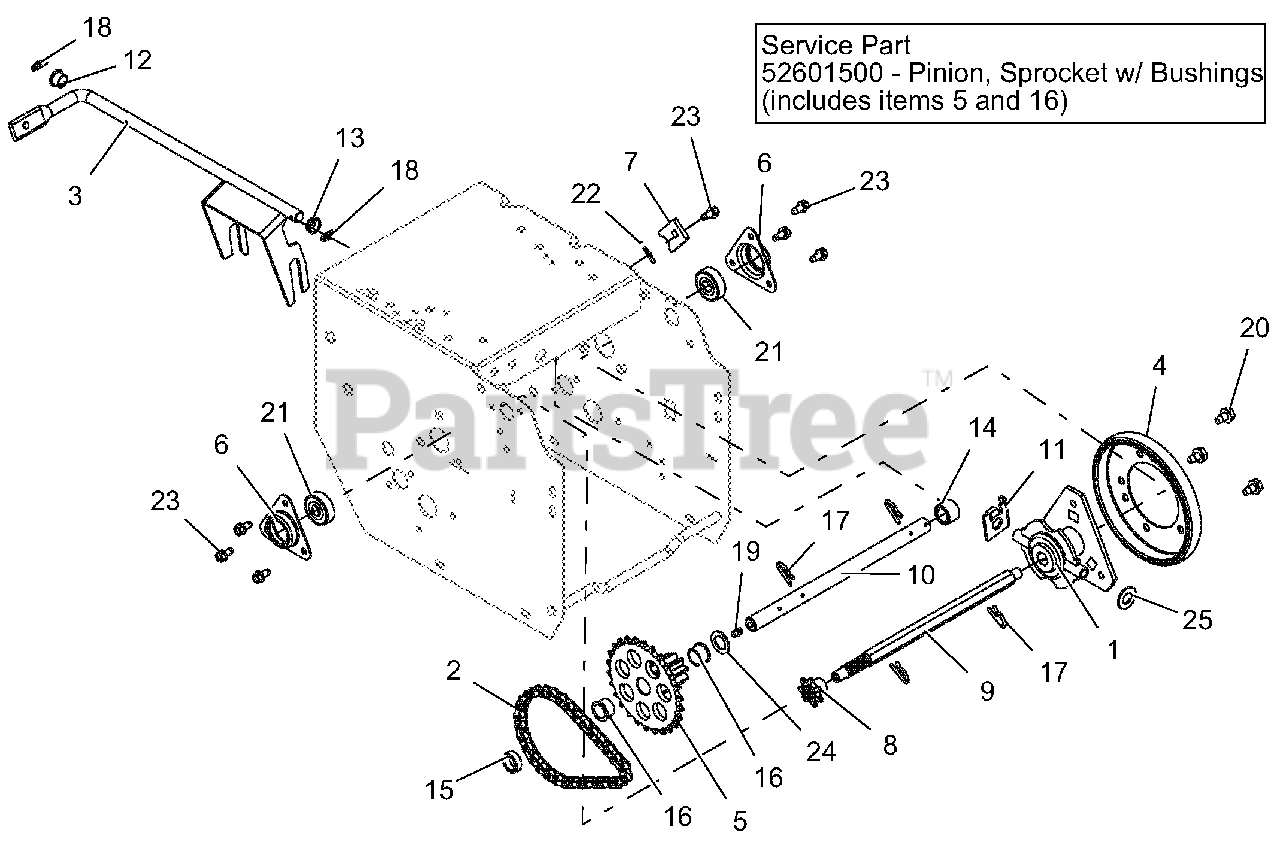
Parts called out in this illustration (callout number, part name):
1	CARRIER, DRIVE DISK
2	CHAIN - #41, 32 PITCHES
3	WELDMENT, SHIFT FORK
4	FRICTION, DISC
5	PINION & SPROCKET
6	FLANGE, BEARING
7	TAB, ANTI ROTATION
8	SPROCKET, PINION 7T W/SPLINE
9	SHAFT, HEX W/SPLINE TRACK
10	SHAFT, PINION TRACK
11	BRACKET, FORMED - SHIFT FORK
12	BUSHING, POLYLINER-.50 SPLIT
13	BUSHING, POLYLINER-.50 SNAPIN
14	SPACER, .635X.880X.611
15	BSHG-SLV, .635X.880X.305
16	BSHG-FLG .625X.750X.500X.875
17	PIN, SPRING CLIP
18	CLIP, SPRING
19	ZERK,FITTING .25X.125 DRIVE IN
20	@SCR-TAP .31-18X.50 HWH TR YWZ
21	BRG-BALL .437X1.375X.437
22	@PIN-GRV .125X1.00 TP E ALLOY
23	SCR-TAP .25-20X.50 HWH TR YWZ
24	WSHR-FL-STL .630X1.005X.062 YZ
25	WSHR-FL-STL .505X1.00X.062YWZC
26	PINION & SPROCKET W/BUSHINGS
